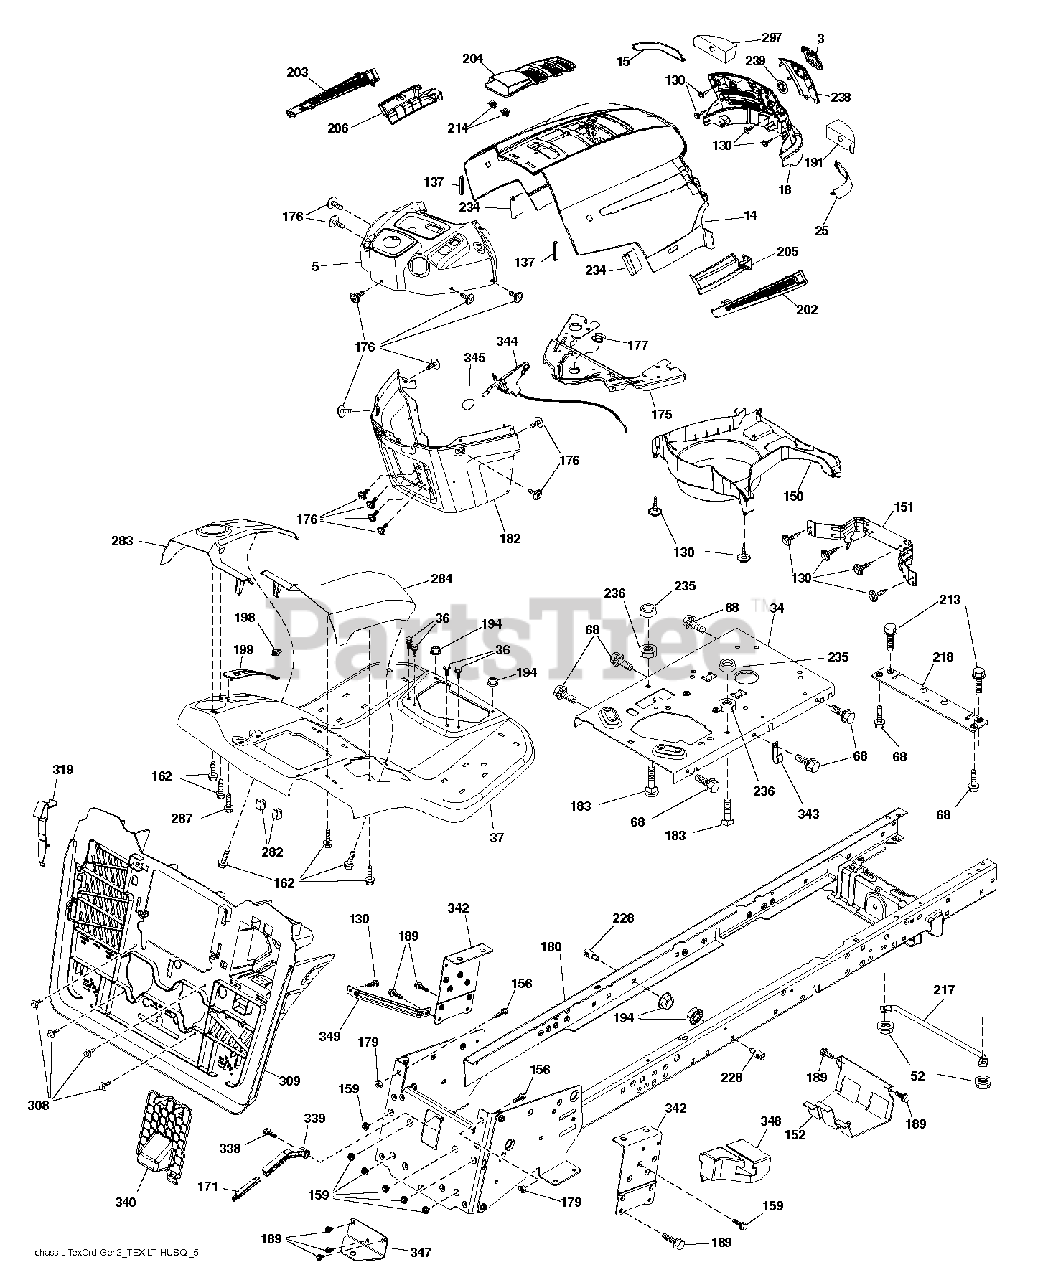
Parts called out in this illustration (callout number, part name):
3	RP LOGO
5	SUBASM.DASH.UPPER.HLT.498
14	HOOD.HUSQVARNA.LT.ORANGE
15	LENS.HUSQVARNA LT.RH
18	GRILLE.SVC.HUSQVARNA.GREY
25	LENS.HUSQVARNA LT.RH
34	PLATE.ENGINE.WELDED.CHASSIS
36	SCREW 5/16"
37	FENDER.TEX.SRD.CRD.FRN.GUARDS
52	LOCKNUT
68	SCREW LT
130	SCREW.#10 X 0.750.BOS
137	BUMPER DASH
151	BRACKET PIVOT
152	SHIELD.BROWNING.PNT.GT.V2
159	SCREW, 3/8-16X3/4
162	SCREW.HI-LO.CONSOLE
171	EXTENSION.BAGGER.FULL.
175	CROSSMEMBER
176	SCREW.#10-24X5/8.RN.QU
177	BUSHING STEERING
182	DASH DASH. LOWER. PREDATOR. LT
183	BOLT.5/16-18X1-1/4 FULL THD
189	SCREW
191	INSERT.REFLECTIVE.RH.
194	NUT LOCK HEX FLANGE 5/16-18
198	INDICATOR.DECK.LIFT.RED
199	PLATE DECK LIFT
202	VENT.SIDE.HUSQVARNA.LT.RT
203	VENT.SIDE.HUSQVARNA.LT.LFT
205	SKIRT.SIDE.HUSQVARNA.LT.RT
206	SKIRT.SIDE.HUSQVARNA.LT.LEFT
213	BOLT
214	CLIP.RETAINER.TINNER.
217	ROD.PIVOT.HOOD
218	X-PIECE.HOOD.STOP.NON/
228	STUD.FASTNER.W/ANTI-ROTATE
234	BUMPER.HOOD.TEX.HUSQVARNA
235	SPACER FENDER
236	NUT.CENTERLOCK.5/16-
238	TRIM.HUSQ LT.668
282	CLIP.RETAINER.CONSOLE.LT.HUSQ
283	CONSOLE.DECKLIFT.CRDII.498
284	CONSOLE.PEDAL.HYDRO
287	SCREW 1/4X20
297	INSERT REFLECTIVE
308	BOLT, 5/16-18 X 1 3/4
338	BOLT BOLT SHOULDER
339	LEVER.BAGGER.FULL.TEX.
342	SUPPORT SUPPORT FENDER
343	CLIP CLIP
344	CONTROL.EZ.MULCH.TEX/CRD
345	RP KNOB.OVAL.TAPERED.3/8-16BLK
347	HITCH TOW
349	BRACKET.SUPPORT.LRVB/CRD
